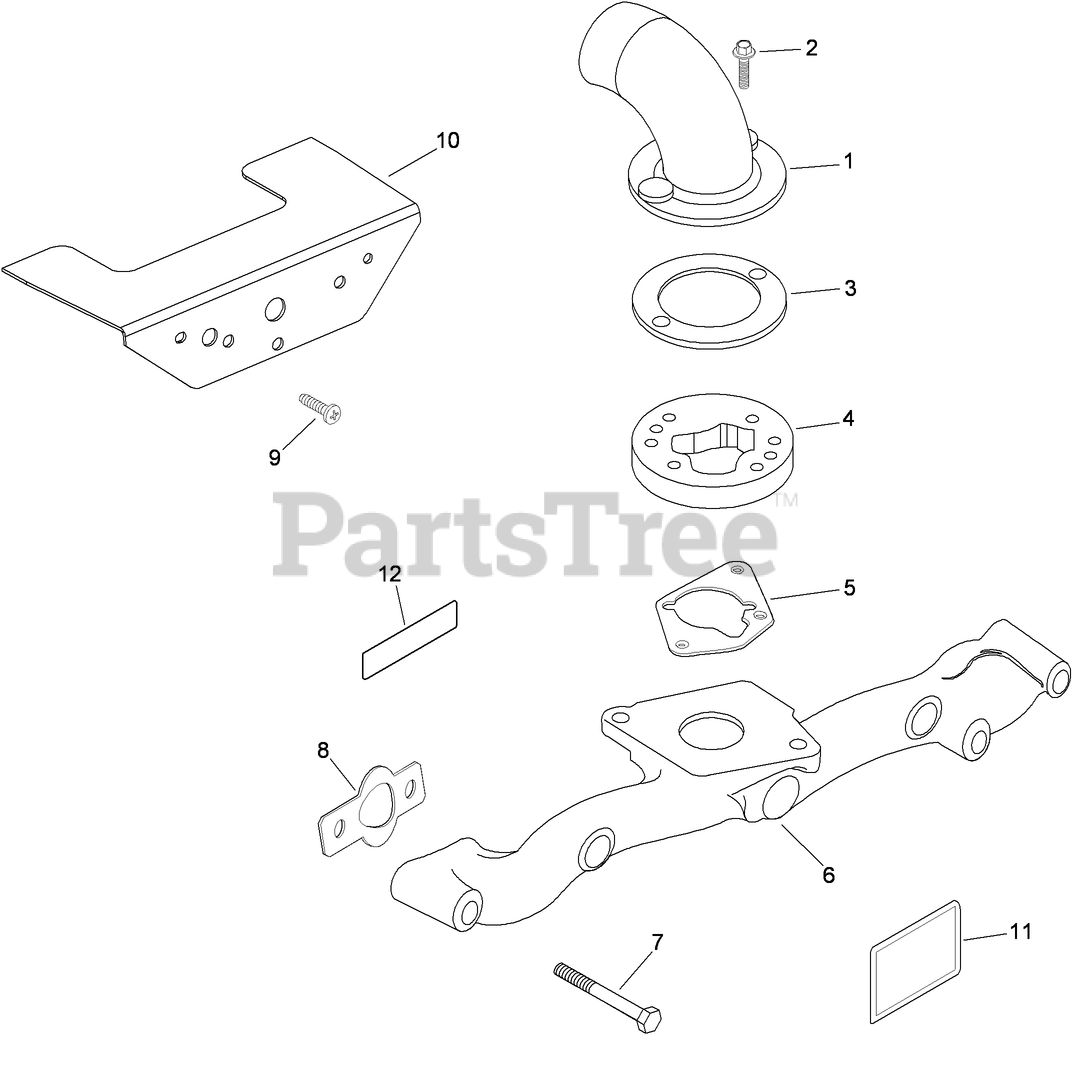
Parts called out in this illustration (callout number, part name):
1	Adapter-Cleaner, Air
2	Screw-HF (M6x1.0x16)
3	Gasket-Adapter
4	Adapter
5	GASKET-BASE, AIR CLEANER
6	Manifold-Intake
7	Screw-HF (M6x1.0x55)
8	Gasket-Manifold, Intake
9	SCREW-PPH (11-16X3/4)
10	Shield-Debris
11	Decal-Cleaner, Air
12	Decal-22HP
